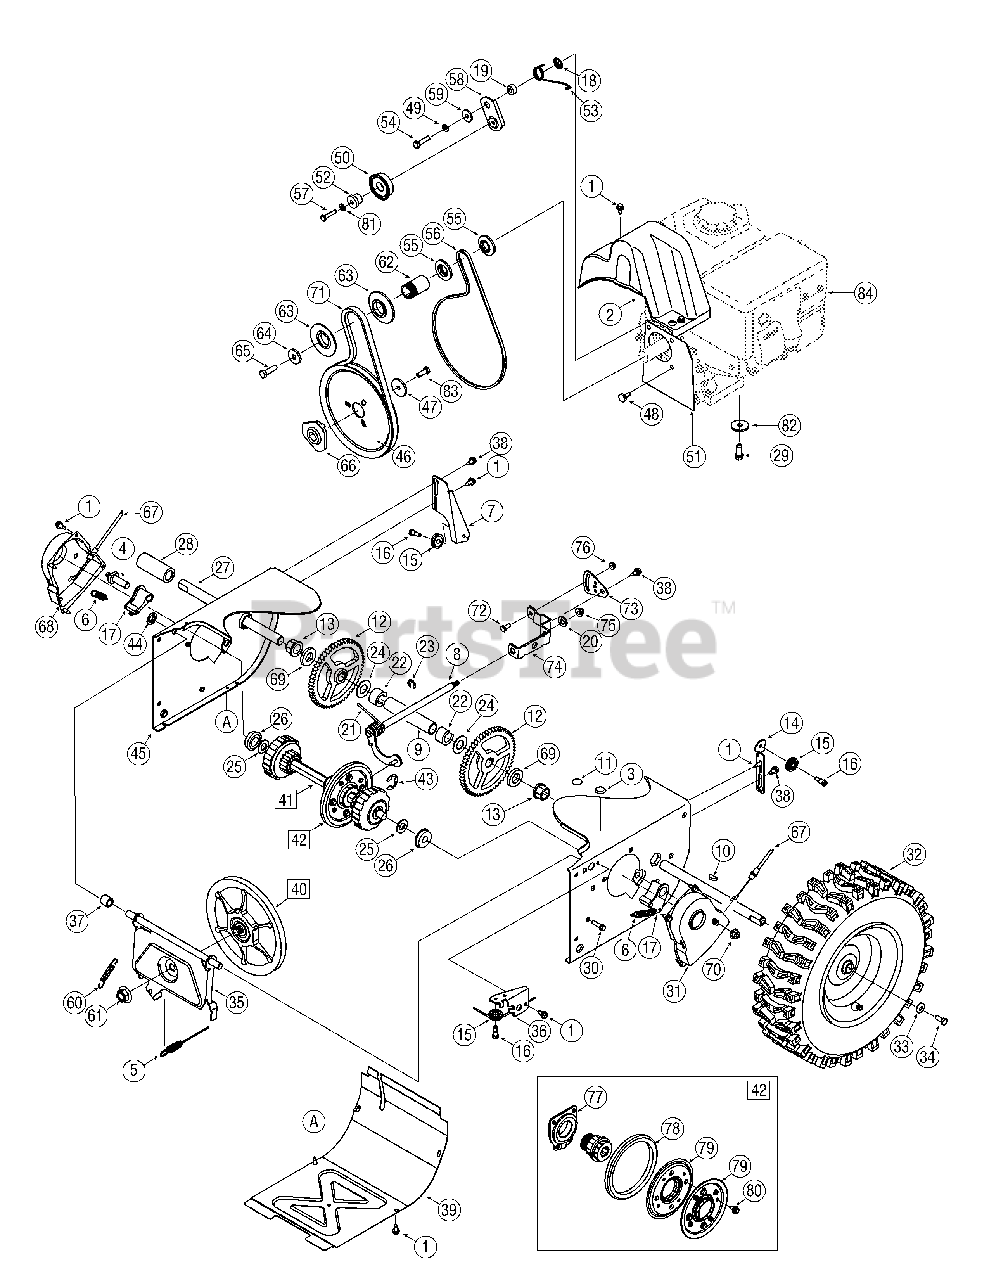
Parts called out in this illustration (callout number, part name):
1	AB Screw, 1/4-20 x 0.625
2	Belt Cover
3	Plug, 3/8 ID
4	Actuator Shaft
5	Drive Clutch Cable
6	Extension Spring
7	Drive Clutch Cable Guide Bracket
8	Shift Rod Assembly
9	Axle Support Tube
10	Hi Pro Key
11	Plug, 1/2 ID
12	Gear, 56T
13	Hex Flange Bearing
14	Auger Clutch Cable Guide Bracket
15	Cable Roller
16	C Screw, 1/4-28 x 0.375
17	Dogg Assembly - LH
17	Dogg Assembly - RH
18	Push-on Nut
20	Washer, Flat
21	Torsion Spring, .750ID x .968 Lg.
22	Spacer
23	E Ring
24	Flat Washer, .76 x 1.49 x .06
25	Flat Washer
26	Ball Bearing
28	Spacer
29	TT Sems Screw, 3/8-16 x 1.0
30	TT Screw, 1/4-20 x 1.0
31	Shaft Retainer - LH
32	Wheel Complete - LH
32	Wheel Complete - RH
33	Bell Washer
34	Hex Bolt, 5/16-24 x 0.75
35	Friction Wheel Support Brkt. Assy.
36	Auger Cable Guide Bracket
37	Spacer
38	Shoulder Screw
39	Frame Cover
40	Friction Wheel Disc Assembly
41	Drive Shaft Assembly
42	Friction Wheel Assembly
43	Retainer Ring
44	Speed Nut
45	Wheel Drive Frame
46	Auger Pulley
47	Flat Washer
48	Shoulder Screw
49	Lock Washer
50	Idler Pulley Assembly
51	Plt., Cvr.
52	Spacer
53	Torsion Spring
54	Hex Screw, 5/16-24 x 1.25
55	Pulley Half
56	Belt, Wheel Drive
57	TT Screw, 1/4-20 x 1.25
58	Drive Clutch Idler Bracket
59	Shoulder Spacer
60	Extension Spring
61	Flange Nut, 5/8-18
62	Spacer
63	Pulley Half
64	Flat Washer
65	Hex Bolt, 3/8-24 x 1.25
66	Pulley Adapter
67	Steering Cable
68	Shaft Retainer - RH
69	Axle Spacer
70	Flange Lock Nut, 3/8-16
71	V-Belt,.500 x 37.00 Lg
72	Hex Screw, 1/4-20 x .620
73	Speed Selector Pivot Bracket
74	Speed Selector Shift Bracket
75	Flange Lock Nut, 5/16-18
76	Flange Lock Nut, 1/4-20
77	Friction Wheel Bearing Assembly
78	Friction Wheel
79	Friction Plate
80	Screw, 1/4-20 x .500
81	Lock Washer
82	Washer, Flat, .38 x 1.38 x .125
83	Hex Bolt, 5/16-24 x 0.875
84	Replacement Engine
